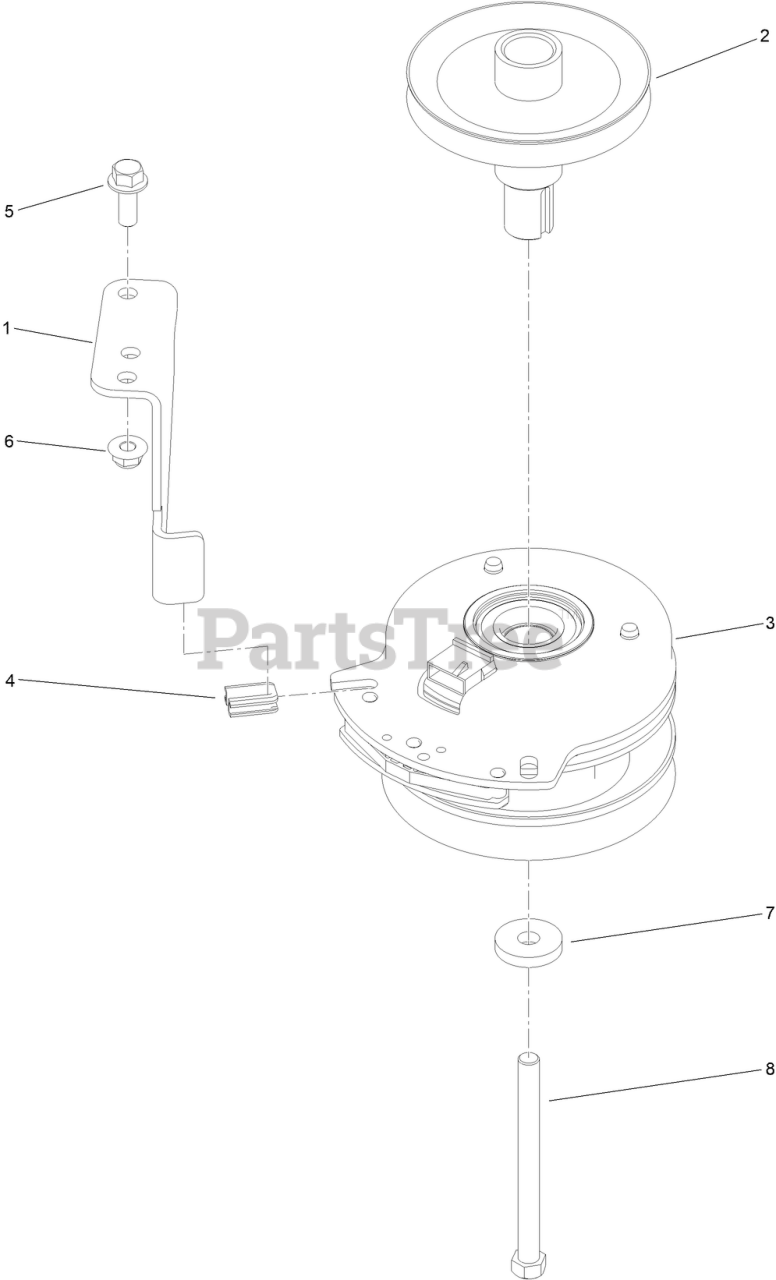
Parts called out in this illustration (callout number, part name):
1	STOP-CLUTCH (WIDE)
2	PULLEY-ENGINE
3	CLUTCH-PTO
4	ISOLATOR-CLUTCH
5	SCREW-HHF
6	NUT-HF, NI
7	WASHER
8	SCREW-HH
